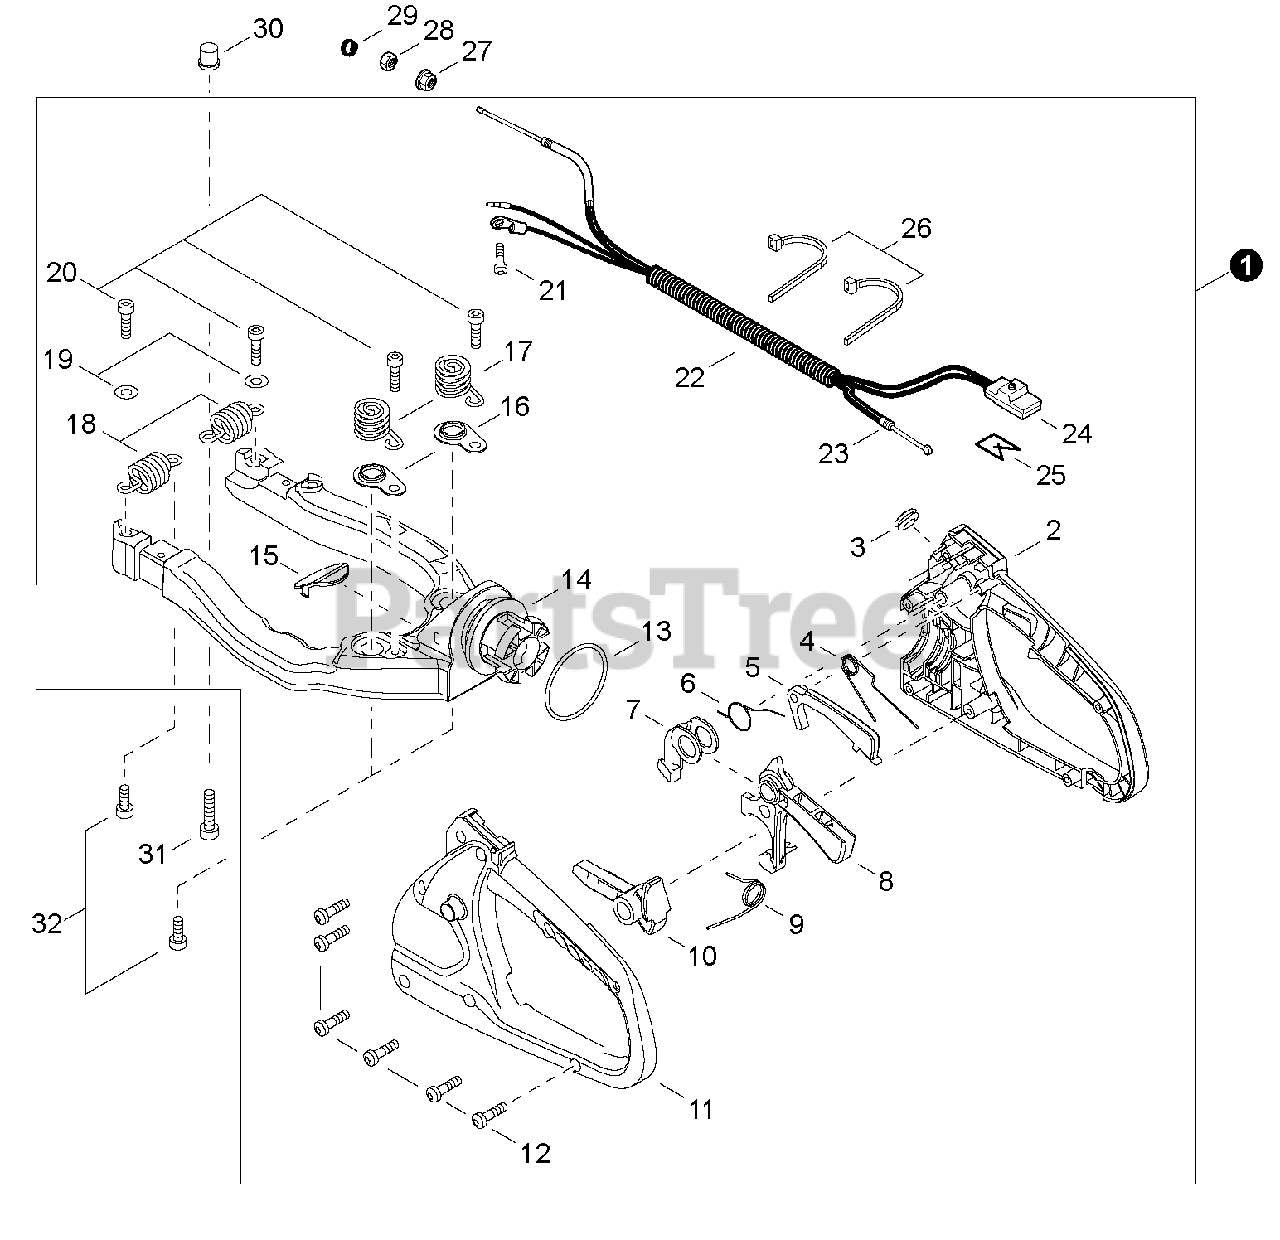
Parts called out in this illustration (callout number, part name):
1	HANDLE ASSY, REAR
2	HANDLE, RIGHT REAR
3	GROMMET
4	SPRING, TORSION
5	LOCKOUT, THROTTLE
6	SPRING, COIL
7	LEVER, THROTTLE
8	TRIGGER, THROTTLE
9	SPRING, TORSION
10	LEVER, HANDLE RELEASE
11	HANDLE, LEFT REAR
12	BOLT, TORX 4×16
14	FRAME
15	COVER, HANDLE
16	HOLDER, SPRING
17	SPRING, COMPRESSION
18	SPRING, COMPRESSION
20	BOLT, TORX 6×20
21	BOLT, TORX 4×8
22	TUBE, PROTECTIVE
23	CABLE, THROTTLE
24	SWITCH, ON-OFF
26	STRAP, TIE
27	NUT, FLANGE M6×1
31	BOLT, TORX 6×25
32	BOLT, TORX 6
